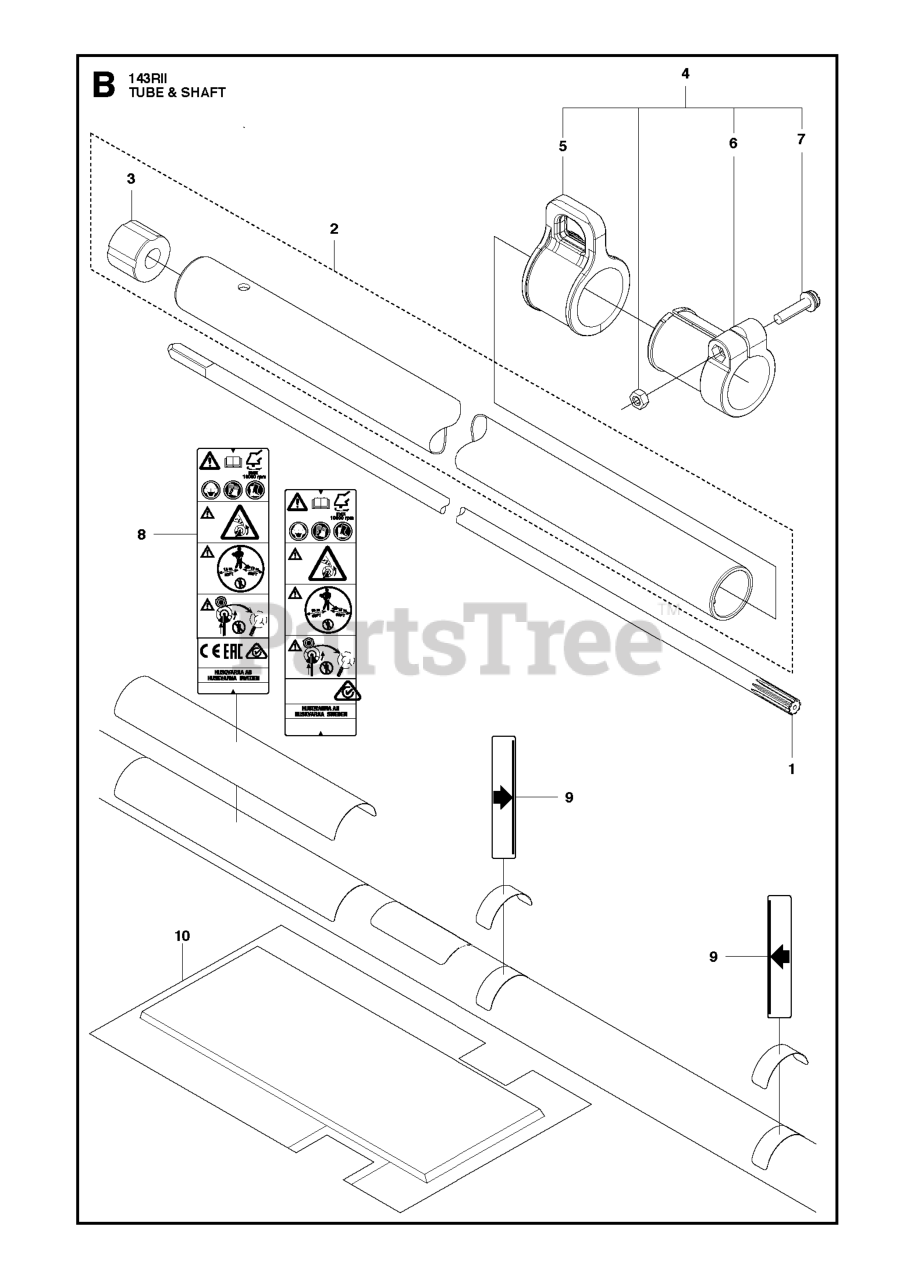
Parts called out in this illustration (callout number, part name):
1	DRIVE SHAFT
2	PIPE COMP.
9	LABEL
10	PROTECTOR (RPLS 405017110)
